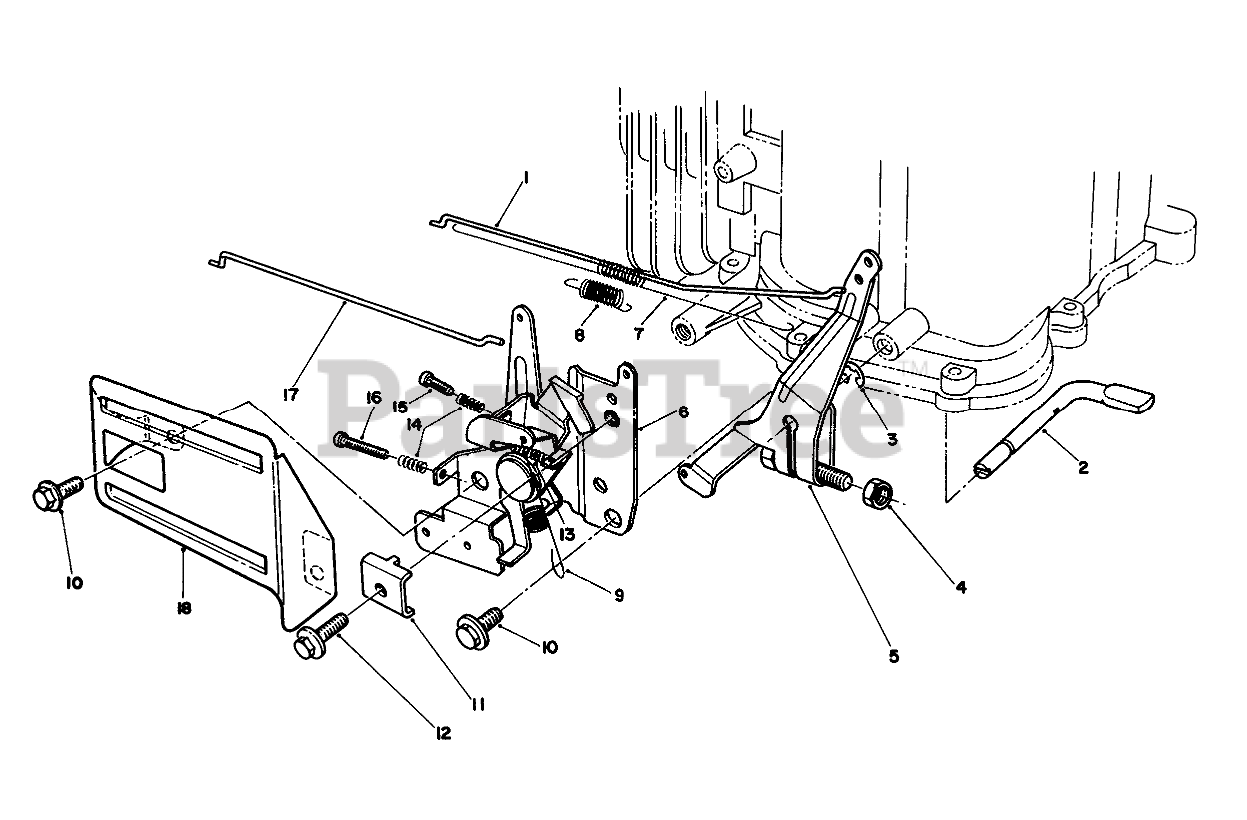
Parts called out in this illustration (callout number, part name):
1	Rod-Carburetor
2	SHAFT
3	E-RING
4	Nut
5	ARM ASM
6	THROTTLE
7	SPRING
8	SPRING
9	SPRING
11	CLAMP-CABLE
13	SPRING
14	Spring
15	SCREW
16	SCREW
17	Rod-Choke
18	THROTTLE GUARD
